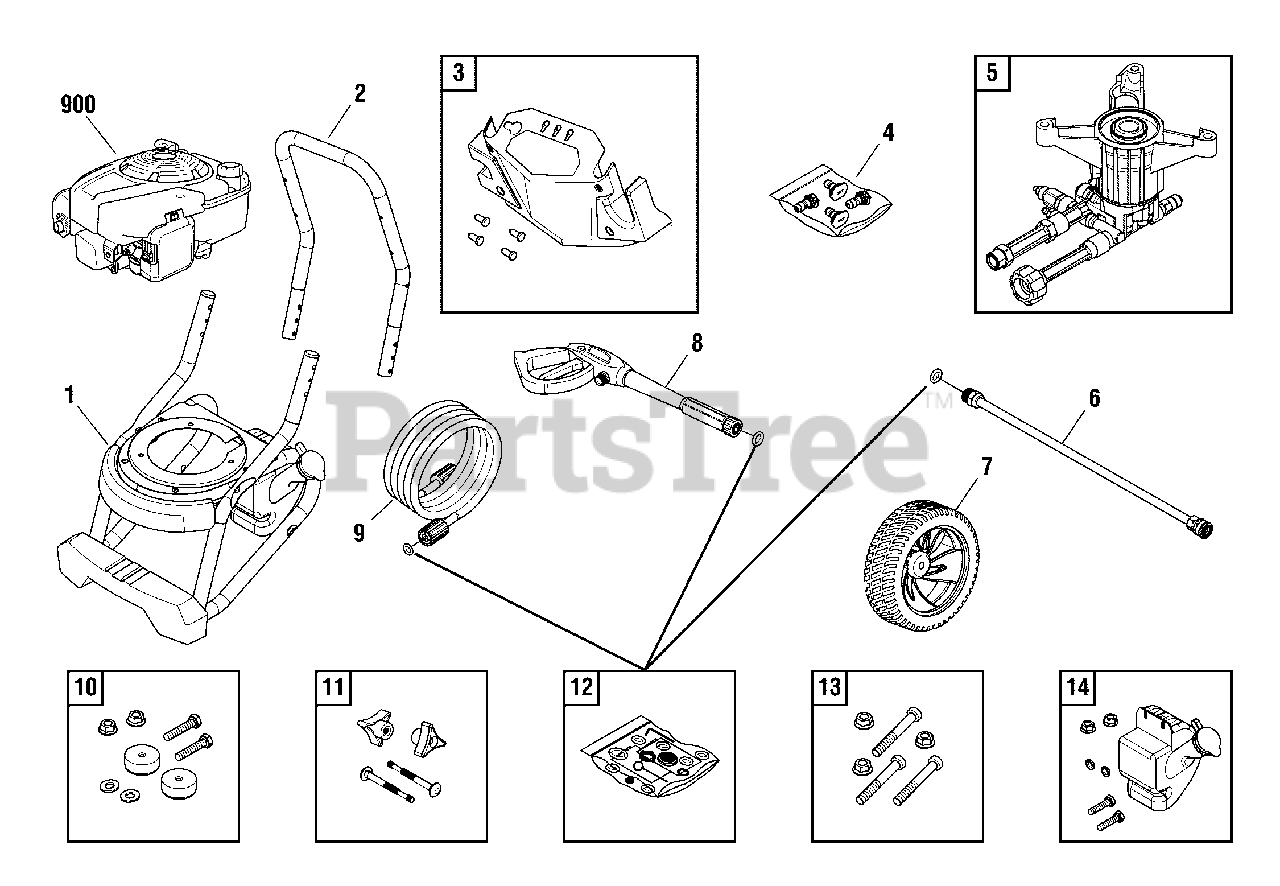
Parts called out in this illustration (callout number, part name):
3	BILLBOARD
4	KIT-QC NOZZLES
8	GUN
9	HOSE
10	MOUNT-VIBRATION
11	KIT-HARDWARE HANDLE
13	KIT-HARDWARE PUMP MOUNTING
900	* ENGINE
